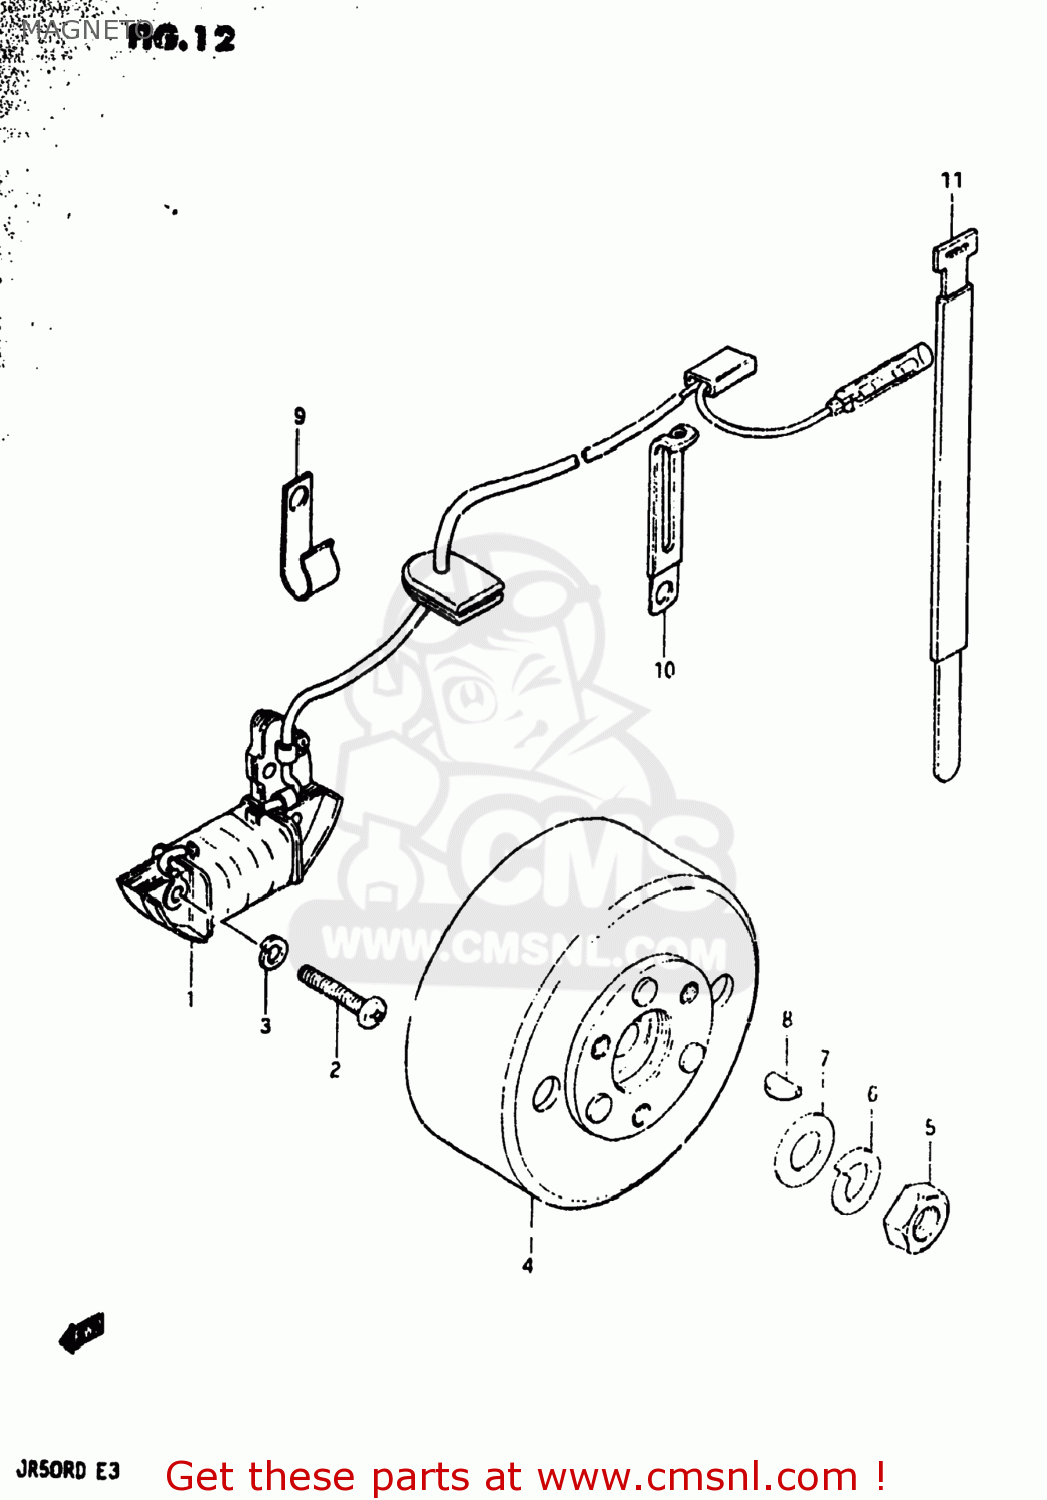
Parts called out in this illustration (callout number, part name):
1	COIL
2	SCREW 4X25
3	LOCK WASHER
4	ROTOR ASSY
5	NUT
6	LOCK WASHER
7	WASHER
8	KEY
9	CLAMP
10	CLAMP L:35
11	CLAMP
